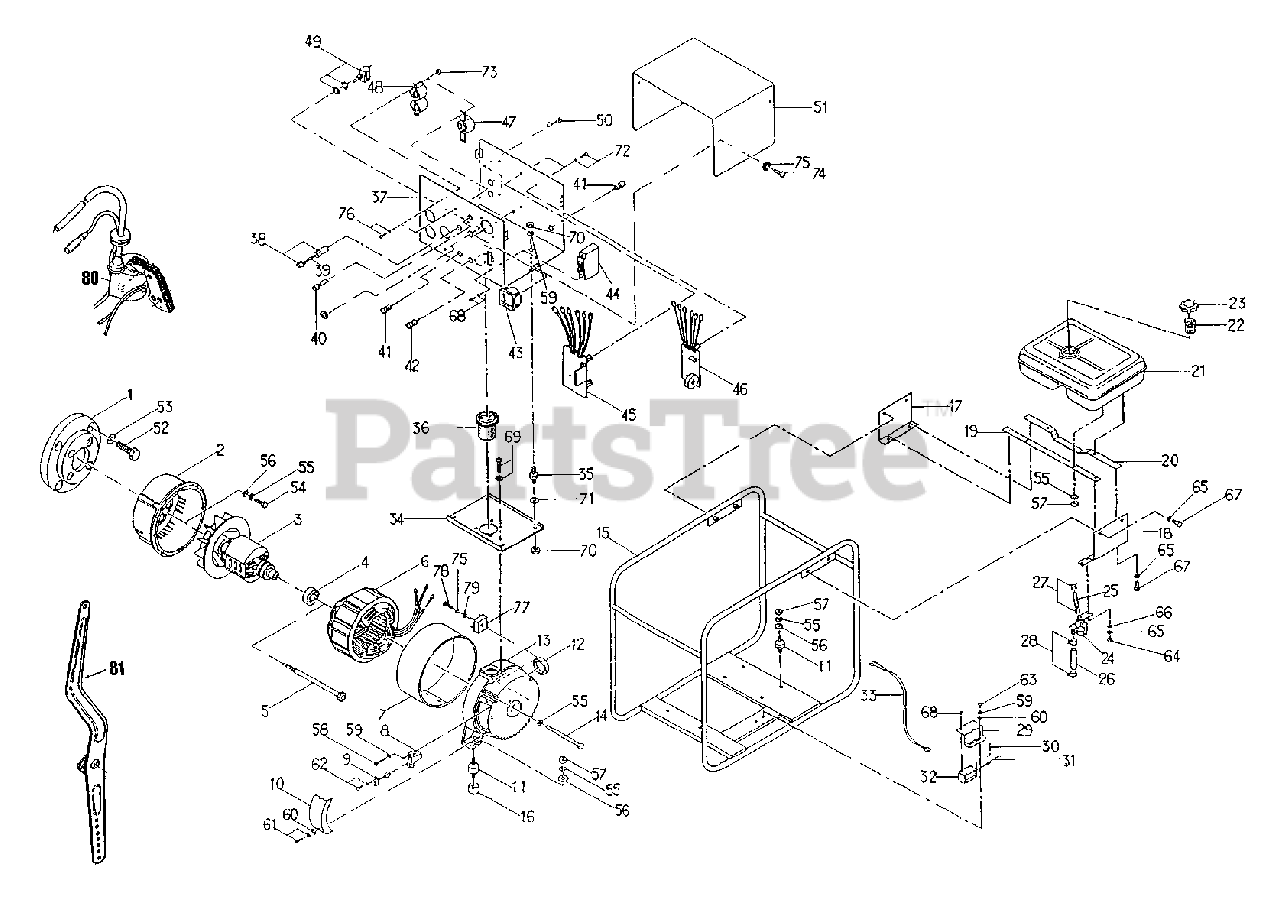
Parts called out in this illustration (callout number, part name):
1	FLANGE
2	BRACKET - FRONT
3	ROTOR ASSY
4	BEARING, BALL
5	THRU BOLT
6	STATOR ASSY
7	STATOR COVER
8	HOLDER, BRUSH
9	BRUSH UNIT
10	COVER, BRUSH
11	RUBBER MOUNT UNIT
12	CAP
13	BRACKET - REAR
14	BOLT
15	TUBE, FRAME
16	SPACER
17	BRACKET, TANK
18	BRACKET, TANK
19	BRACKET, FUEL TANK
20	BRACKET, FUEL TANK
21	FUEL TANK ASSY
22	FILTER, FUEL
23	CAP ASSY
24	STRAINER, FUEL
25	HOSE - RUBBER
26	HOSE - RUBBER
27	CLAMP, HOSE
28	CLAMP, HOSE
29	BRACKET, SOLENOID
30	PIN, SPLIT
31	SPRING
32	SOLENOID
33	WIRE ASSY
34	BOX BASE
35	RUBBER MOUNT
36	BUSHING
37	CONTROL BOX ASSY
38	HOLDER, FUSE
39	FUSE
40	NEON LAMP - 110V
41	OUTPUT TERMINAL - BLACK
42	OUTPUT TERMINAL - RED
43	METER - 150V
44	BREAKER - 40A
45	AVR UNIT
46	AUTOMATIC IDLE RETURN
47	OUTLET - 250V 15A
48	OUTLET - 125V 15A X 2
50	CORD BUSHING
51	BOX COVER
52	BOLT
53	LOCKWASHER
54	BOLT - 8X20
55	LOCKWASHER - 8
56	WASHER - 8
57	NUT - 8
58	SCREW - 5X20
59	LOCKWASHER - 5
60	WASHER - 5
61	SCREW - 5X10 -- TAPPING
62	SCREW 4X6 -- TAPPING - BRASS
63	BOLT - 5X12
64	BOLT - 6X12
65	LOCKWASHER
66	WASHER - 6
67	BOLT - 6X15
68	SCREW - 3X8 -- TAPPING
69	SCREW - 5X15 -- TAPPING
70	NUT - 5
71	LOCKWASHER - 5
72	SCREW - 4X6 -- TAPPING
73	NUT - 4
74	BOLT - 4X10
75	LOCKWASHER - 4
76	SCREW - 4X10 -- TAPPING
77	BLOCK, DIODE
78	SCREW - 4X18
79	WASHER - 4
80	IGNITION UNIT
81	LEVER, GOVERNOR
